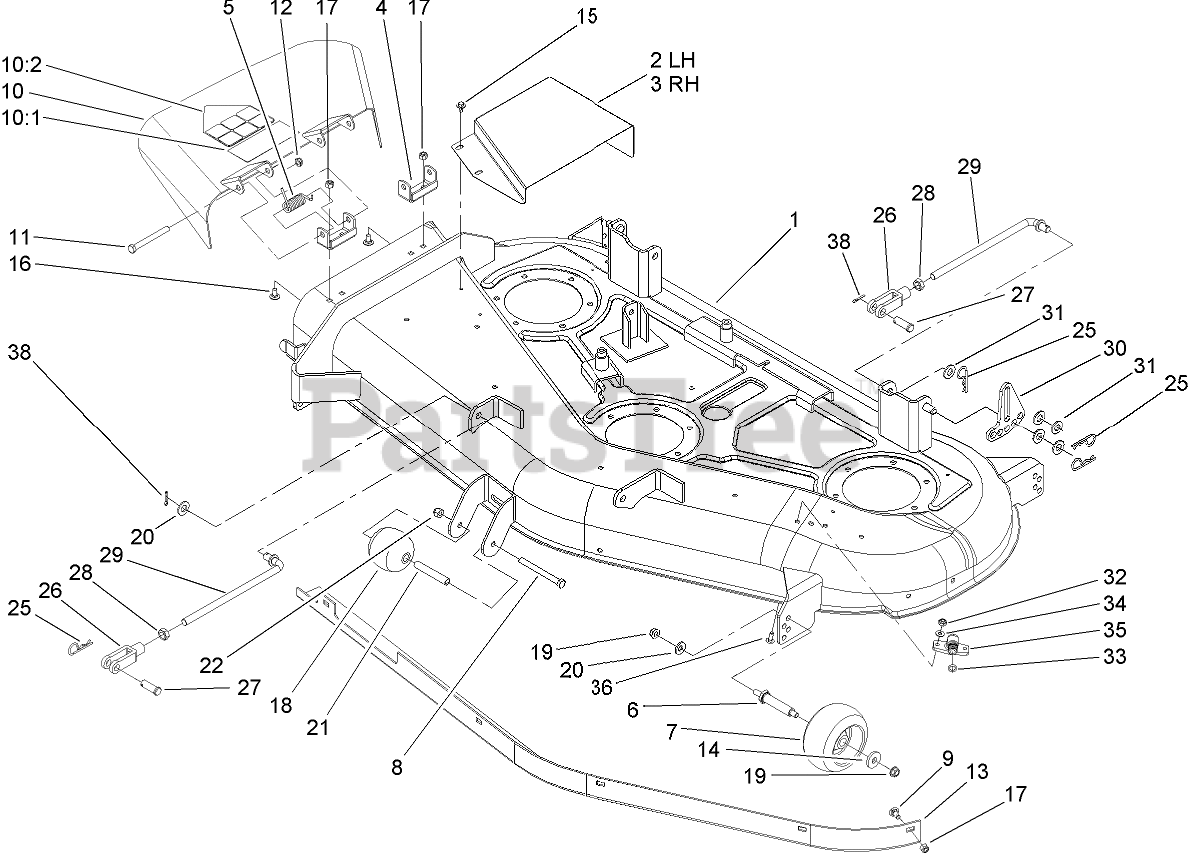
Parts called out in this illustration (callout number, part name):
1	52 INCH DECK ASM
2	COVER-BELT, LH
3	COVER-BELT, RH
4	BRACKET-PIVOT
5	SPRING
6	SPACER
7	ROLLER-SCALP, ANTI
8	SCREW-HH
9	SCREW-CARR
10	DEFLECTOR ASM
10:1	DECAL-DANGER
10:2	DECAL-DANGER
11	SCREW-HH
12	NUT-HEX
14	WASHER
15	SCREW-HHFTF
16	SCREW-CARR
17	NUT-LOCK, NI
18	ROLLER
19	NUT-HHF, WHIZ
20	WASHER-BELLEVILLE
21	TUBE-SPACER, WHEEL
22	NUT-LOCK, NI
25	PIN-COTTER
26	CLEVIS
27	PIN-CLEVIS
28	NUT-JAM
29	ROD-TRUNION
30	LINK-HOC, ADJUSTING
31	WASHER-FLAT
32	NUT-LOCK, NI
33	O-RING
34	WASHER-FLAT
35	FITTING-WASHOUT
36	BOLT-CARR
38	PIN-COTTER
